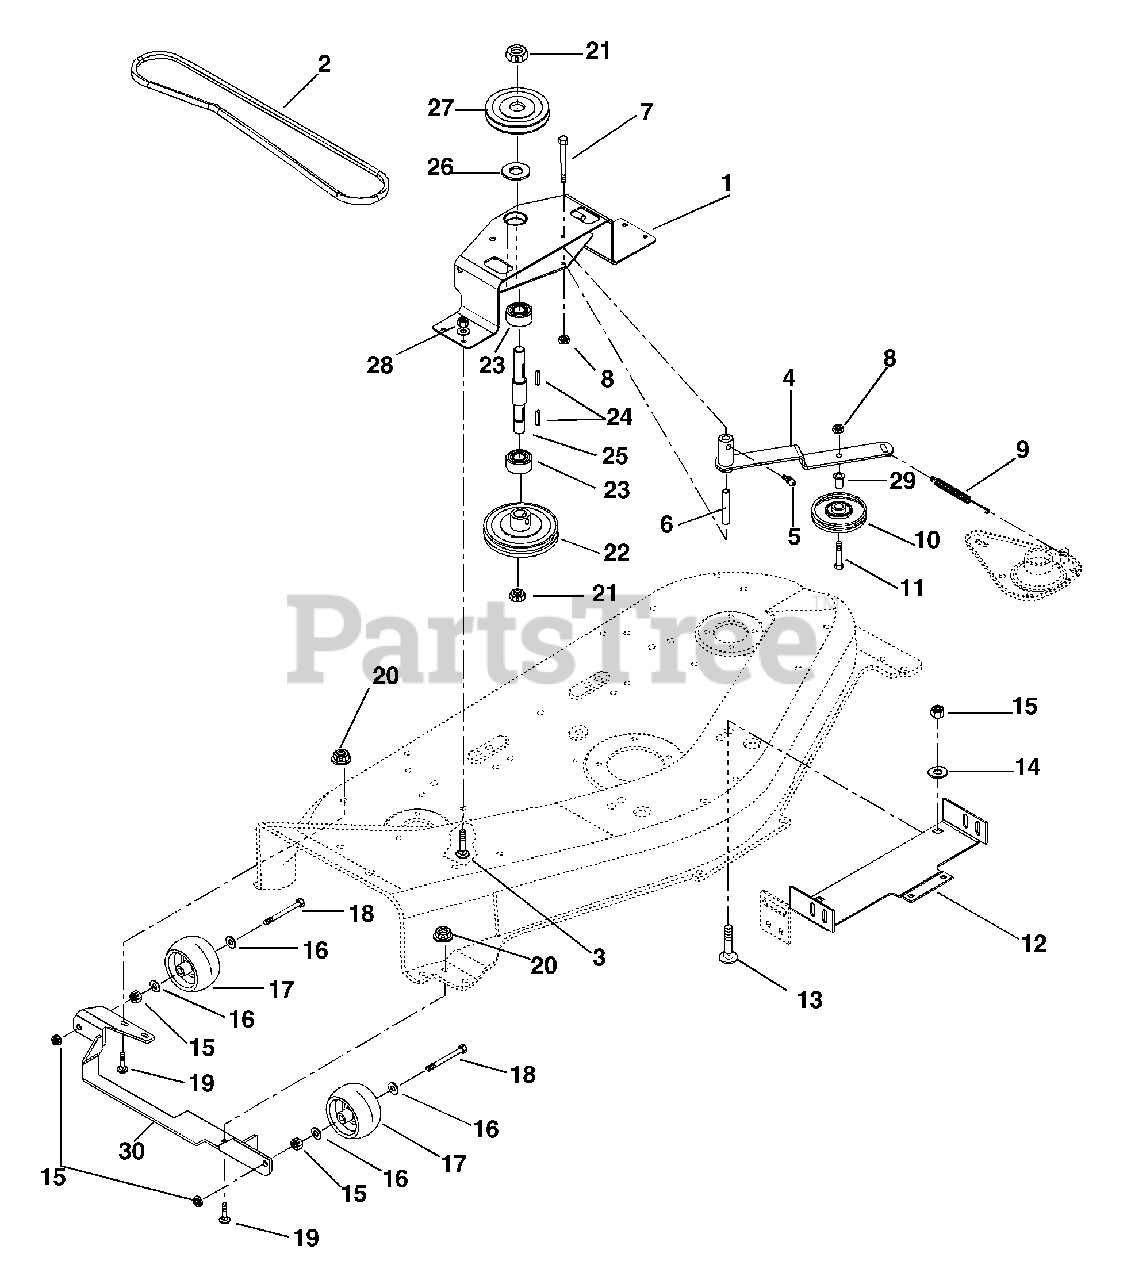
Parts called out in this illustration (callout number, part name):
1	HOUSING-JACKSHAFT
2	V-BELT, HA-RAW EDGE
3	BLT-RDHDSQSHK.31-18X.75 GR2 YW
4	ARM-IDLER
5	FTG-LUBE .25-28X.256 YWZC
6	SPACER .334X.500X2.73
7	@BLT-HEX .31-18X3.50 GR5 YWZC
8	@NUT-LK-CTR .38-16 YWZC
9	SG-TENS .113X.812X7.00
10	IDLER, PLASTIC, 4.00 X .50 ID
11	@BLT-HEX .38-16X1.50 GR5 YWZC
12	BRACE-FRONT
13	@BLT-RDHDSQNK .50-13X1.00 G5YZ
14	WSHR-FL-STL .505X.880X.072 YWZ
15	@NUT-LK-CTR .50-13 YWZC
16	WSHR-FL-STL .505X.880X.072 YWZ
17	WHEEL 5 X 3
18	@BLT-HEX .50-13X4.00 GR5 YWZC
19	@BLT-RDHDSQNK .31-18X.75 G5YZ
20	@NUT-LK-TOP-FLG .31-18 YWZC
21	@NUT-LK-CTR .75-10 YWZC
22	PLY-V 6.00 X .75 W/KEY
23	BRG-BALL .750X1.781X.61
24	KEY-SQ .187 X .50 X .187
25	JACKSHAFT
26	WSHR-FL-STL .755X1.25X.125 YZ
28	@NUT-LK-CTR .31-18 YWZC
29	SPACER -FLANGED .390X.500X.781
30	MOUNT ROLLER
31	@WSHR-FL-STL.281X.62X.065 YWZC
32	@NUT-LK-CTR .25-20 YWZC
